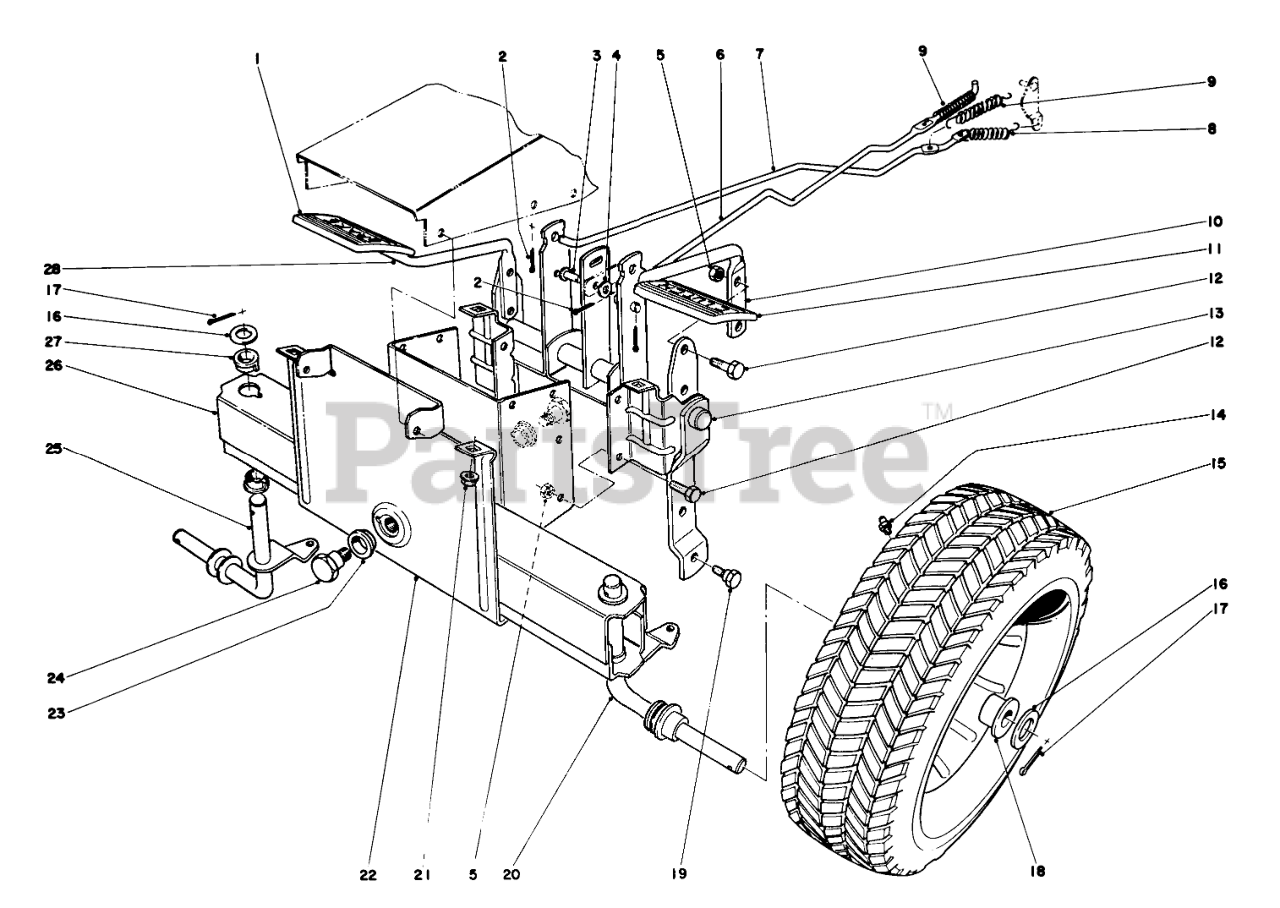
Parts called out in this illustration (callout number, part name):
1	PAD-BRAKE
2	PIN-COTTER
3	PIN-CLEVIS
4	WASHER-PLAIN
5	NUT-LOCK, CONE
6	Clutch Rod
7	Rod Brake
8	Spring, Brake
9	Spring
10	Clutch Pedal
11	CLUTCH PAD
12	SCREW-HH
13	Control Shaft
14	FITTING-GREASE
15	Tire & Rim (Inc. Ref. No. 14 & 18)
16	WASHER-FLAT
17	PIN-COTTER
18	BUSHING
19	Screw
20	Spindle L. H.
21	NUT-HF
22	Frame Lower Front
23	Bushing
25	Spindle R. H.
26	Front Axle
27	Bushing
28	Brake Pedal
